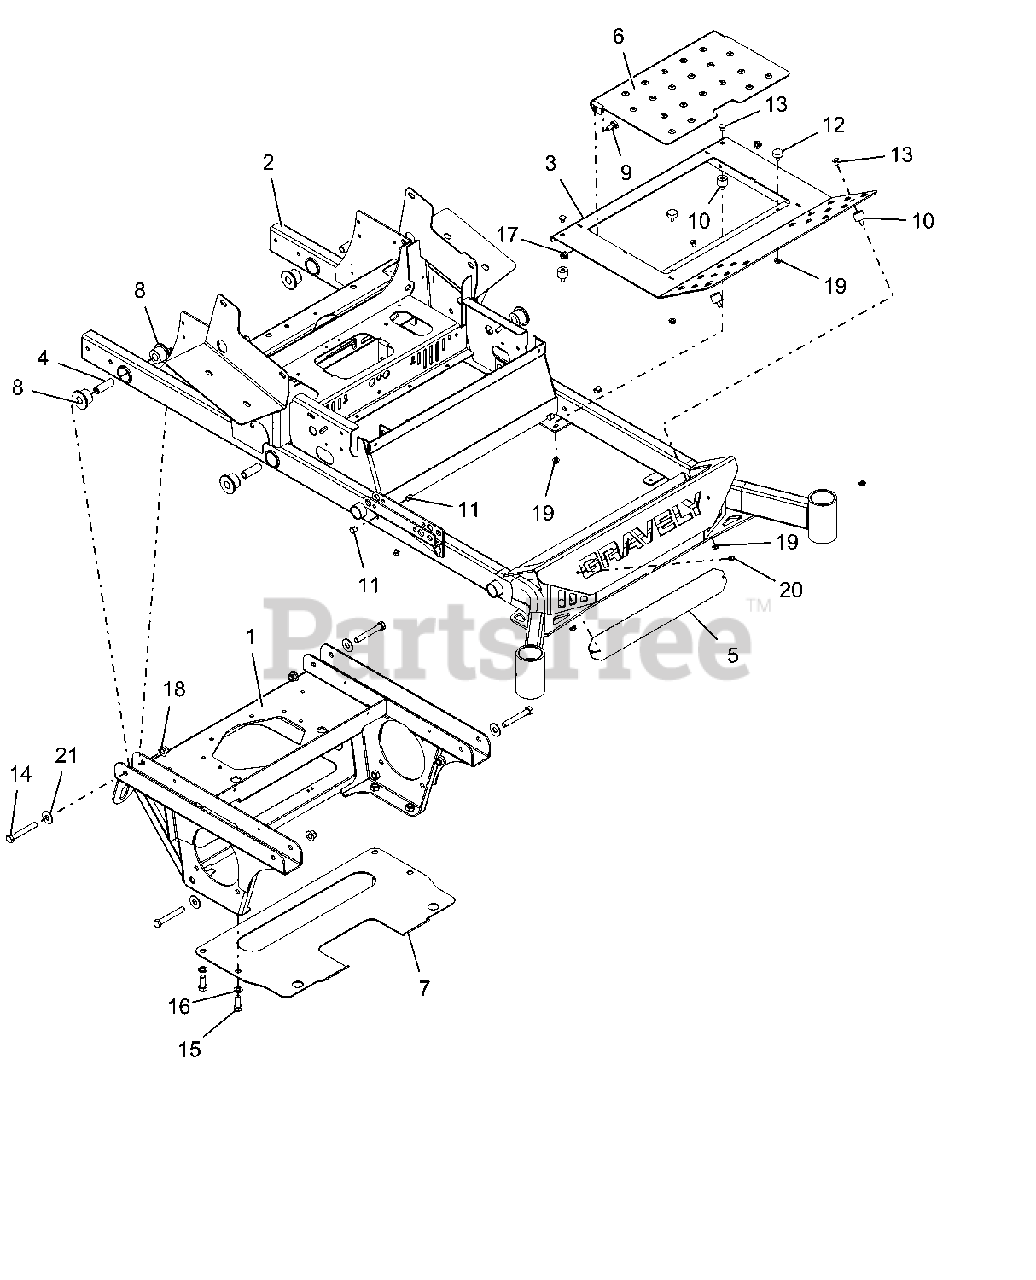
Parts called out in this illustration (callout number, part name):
1	PT200/400 AXLE/ENG FRM WMT-RED
2	52-60"PT200/400 FRAME W/DECALS
3	FOOTPLATE WLDMT W/SAFETY DECAL
4	BSHG-SLV .50X.75X2.23
5	BUMPER LOGO BACKING PLATE -BLK
6	INSPECTION PANEL W/SAFTY DECAL
7	PLATE-TRANSMISSION SKID
8	BSHG-FLG .75X1.51X1.13X2.0 URE
9	BLT,SHLDR EP .38-16X.30 HEX YZ
10	BUMPER,STUD MNTD W/FEMALE INSR
11	PLUG, HOLE .50
12	BUMPER, RUBBER
13	BLT-RDHDSQNK .31-18X.50 G5YZ
14	@BLT-HEX .50-13X3.50 GR5 YWZC
15	@BLT-HEX .50-13X1.25 GR5 YWZC
16	@WSHR-LK .50X.125 REG YWZC
17	@NUT-LK-NYL-FLG .38-16 YWZC
18	@NUT-LK-NYL-FLG .50-13 YWZC
19	NUT-SPNLK-FLG .312-18 YWZC
20	SCR-TAP .25-20X.50 HWH TR YWZ
21	@WSHR-FL-STL.563X1.38X.109YWZC
